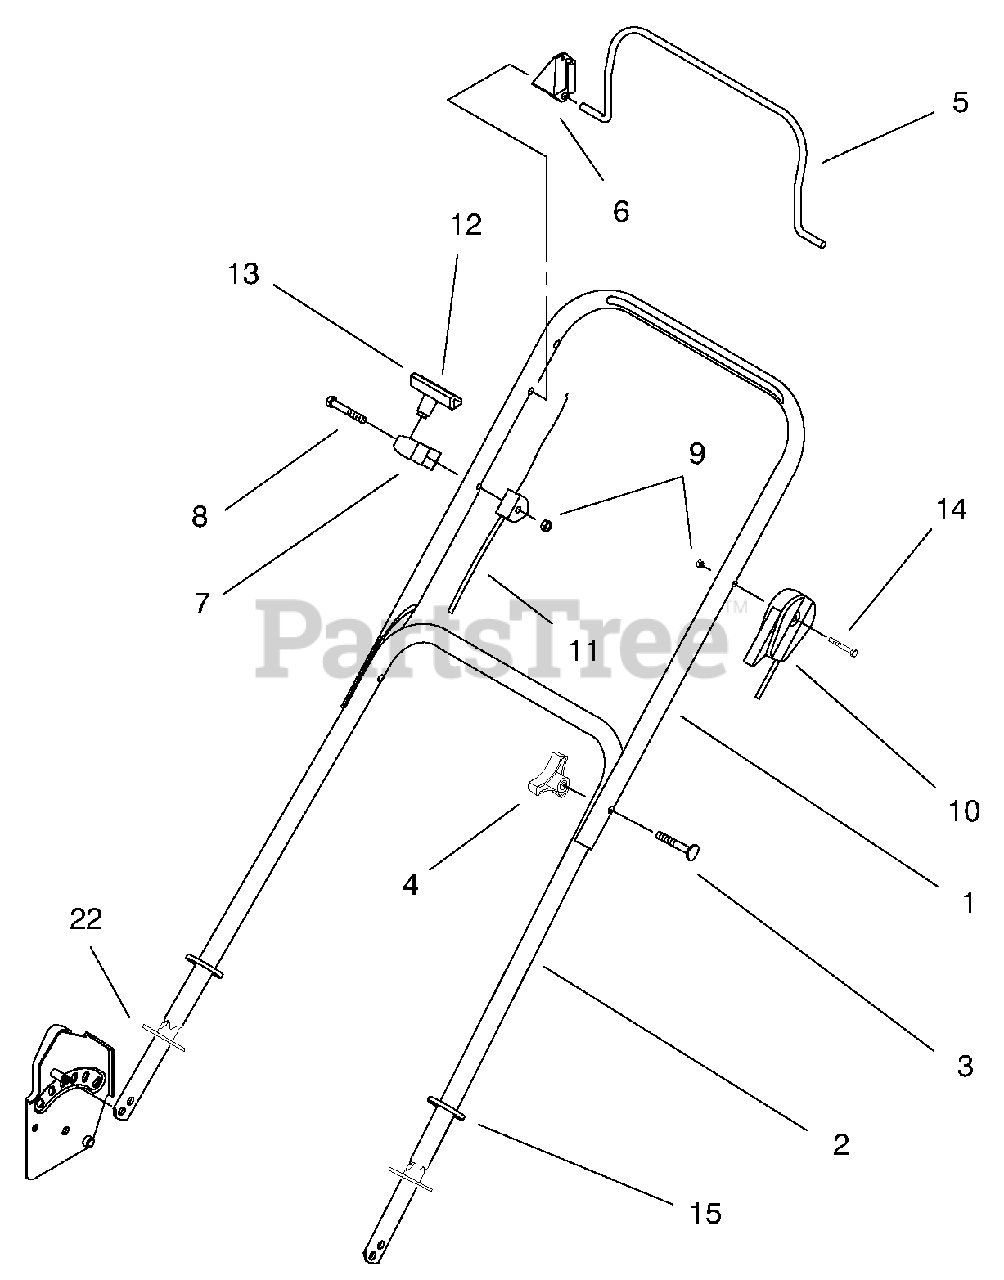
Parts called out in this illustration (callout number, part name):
1	Handle Section-Upper
2	Handle Section-Lower
3	Screw-Handle
5	Bail-Flywheel Brake
6	Stop-Pivot
7	Guide-Rope
9	Nut-Lock
10	Cable-Throttle
11	Cable-Flywheel Brake
12	Clip-Rope
13	Handle-Starter
14	Screw-HH
15	Tie-Cable
22	Handle-Guard
